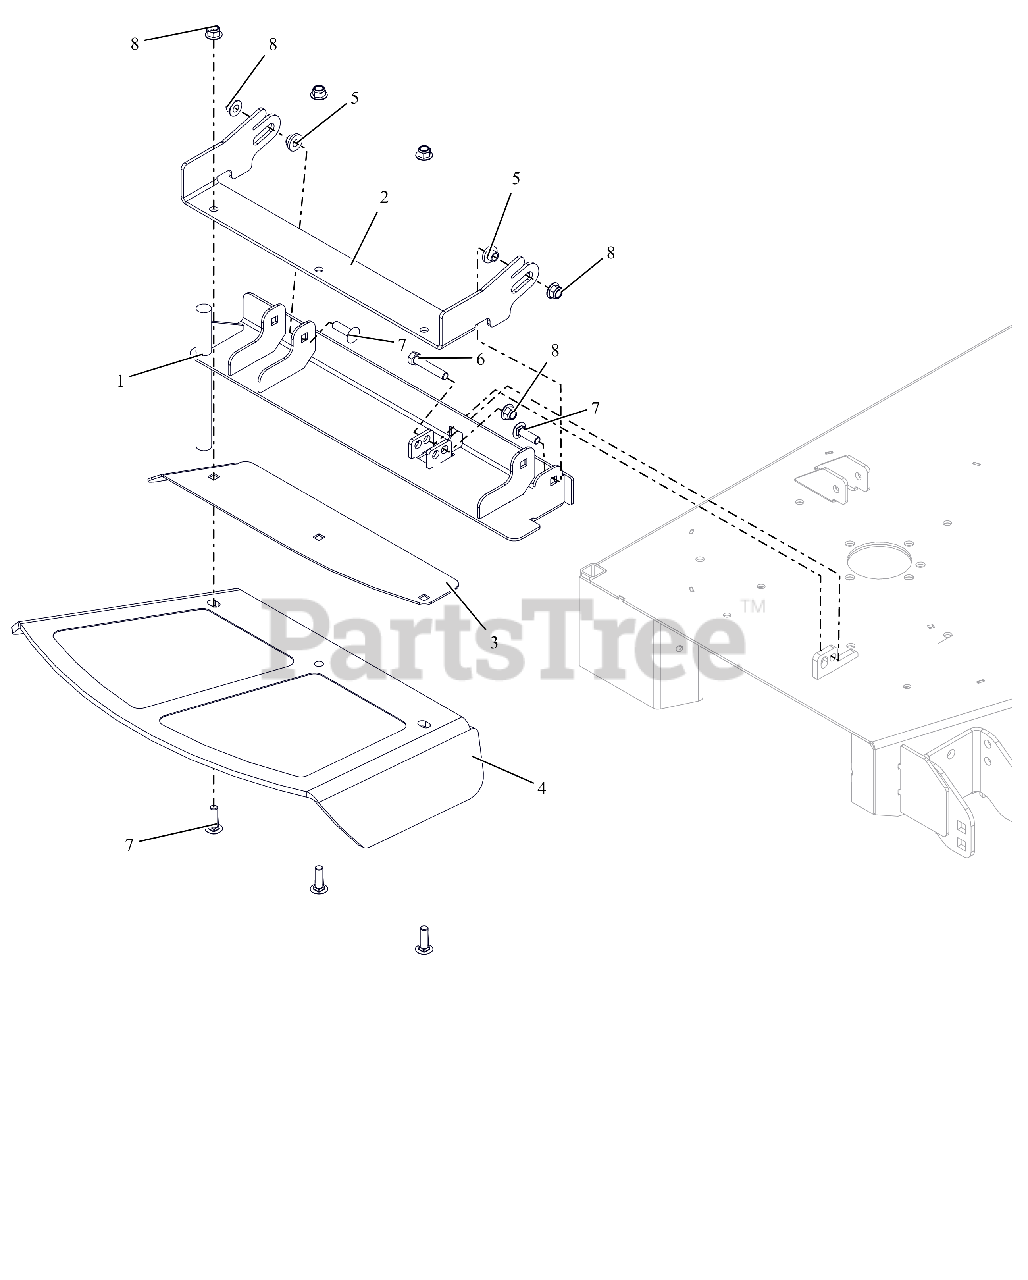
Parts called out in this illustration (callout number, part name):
1	48-60 DISCH CHT MTG WMT W/SAFE
2	48-60" CHUTE MTG BRKT - RED
3	48-60 DISCH CHUTE CLMP PLT-RED
4	CHUTE,48-60" FRMD RUBBER DISCH
5	BSHG-FLG .385X.500X.875X.406
6	BLT,HEX .38-16X2.00 G5 ZCC
7	BLT,RHSSN .38-16X1.25 G5 ZCC
8	NUT,NYL-FLG .38-16 GF ZCC
